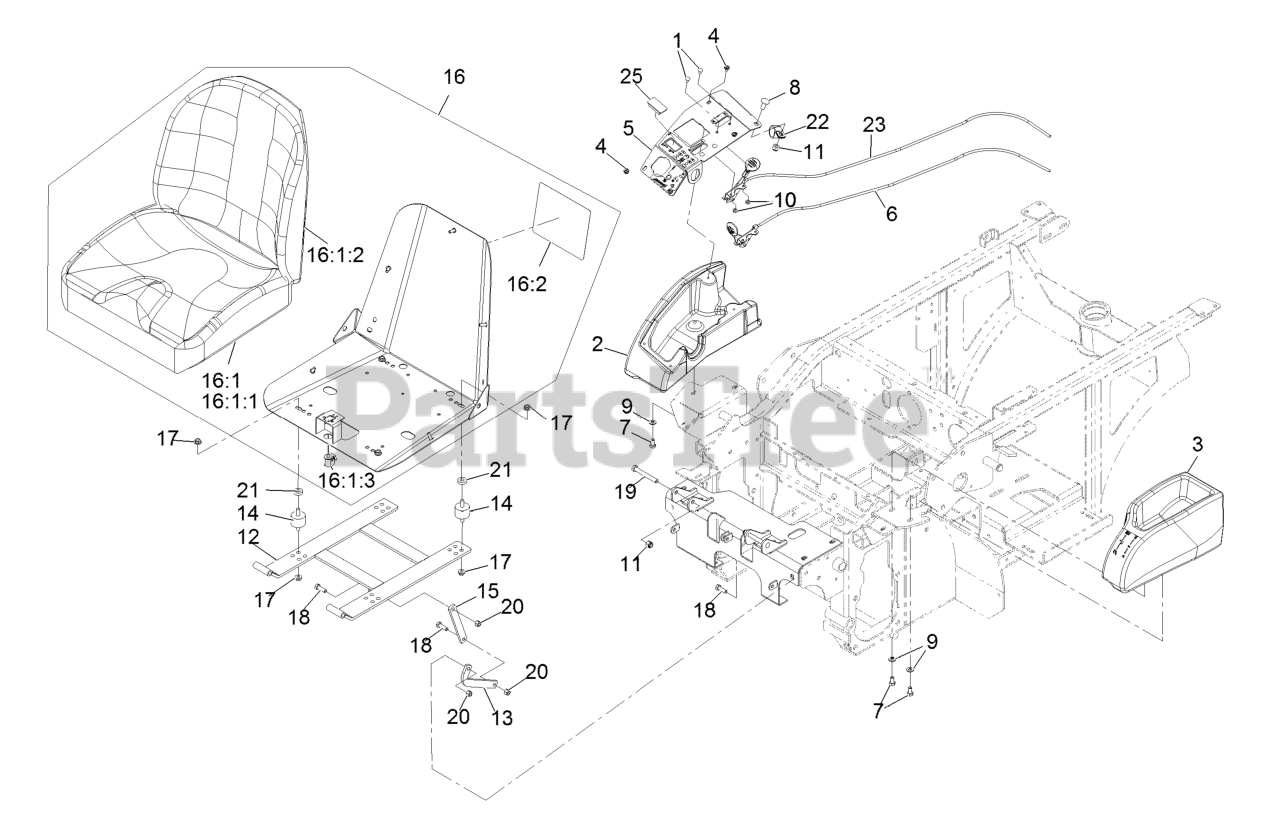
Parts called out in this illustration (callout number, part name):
1	BOLT-CARR
2	CONSOLE-RH
4	SCREW-PPH
5	CONTROL PANEL ASM
6	CABLE-THROTTLE
7	SCREW-HH
8	SCREW-CARR
9	WASHER-PLAIN
10	NUT-LOCK, NI
11	NUT-LOCK, NI
12	FRAME-SEAT
13	LINK-SEAT STOP
14	MOUNT-VIBRATION, RUBBER
15	LINK-SEAT
16:1	Asm-Seat
16:1:1	ASM-SEAT BOTTOM CUSHION
16:1:2	CUSHION,SEAT BACK
16:1:3	SWITCH-BAIL
16:2	DECAL-SERVICE AID
18	SCREW-HH
19	SCREW-CARR
20	NUT-LOCK, NI
21	SPACER
22	CLIP-LOOM
23	CABLE-CHOKE
25	PLUG-HOLE
